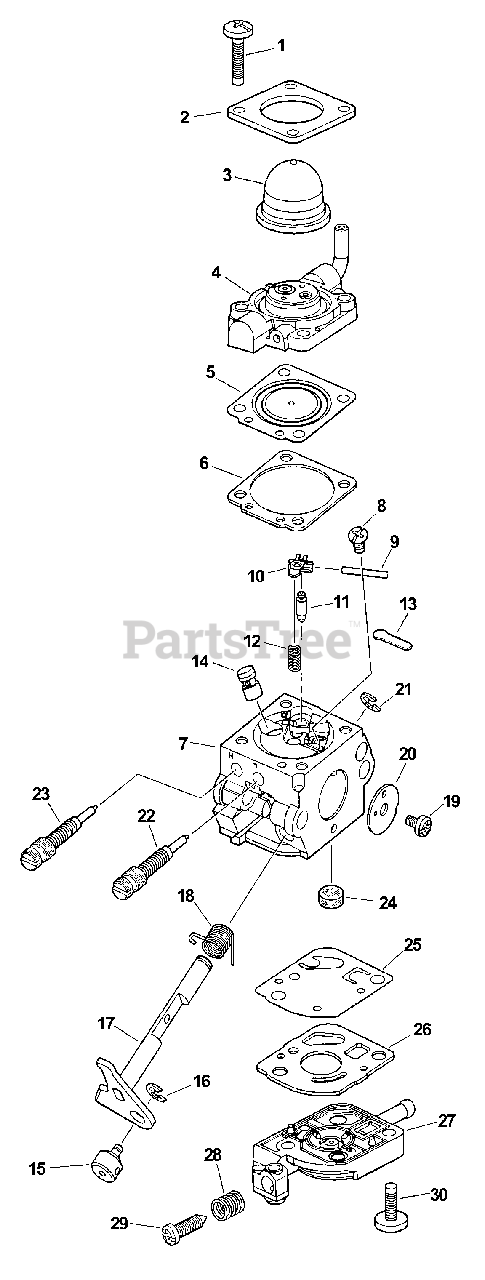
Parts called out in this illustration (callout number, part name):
1	SCREW, RETAINER
2	RETAINER, PURGE BULB
3	BULB, PURGE
4	BASE, PURGE
5	DIAPHRAGM, METERING
6	GASKET, METERING
7	BODY, CARBURETOR
8	SCREW, METERING LEVER PIN
9	PIN, METERING LEVER
10	LEVER, METERING
11	VALVE, INLET NEEDLE
12	SPRING, METERING LEVER
13	PLUG, WELCH
14	NOZZLE, CHECK VALVE
16	RING, RETAINING
17	SHAFT, THROTTLE
18	SPRING, RETURN
20	VALVE, THROTTLE
21	RING, RETAINING
22	NEEDLE - LOW SPEED
23	NEEDLE - HIGH SPEED
24	STRAINER
25	DIAPHRAGM, PURGE
26	GASKET, PURGE
27	BASE, PURGE
28	SPRING, IDLE ADJUST
29	SCREW, IDLE ADJUST
30	SCREW, PUMP COVER
